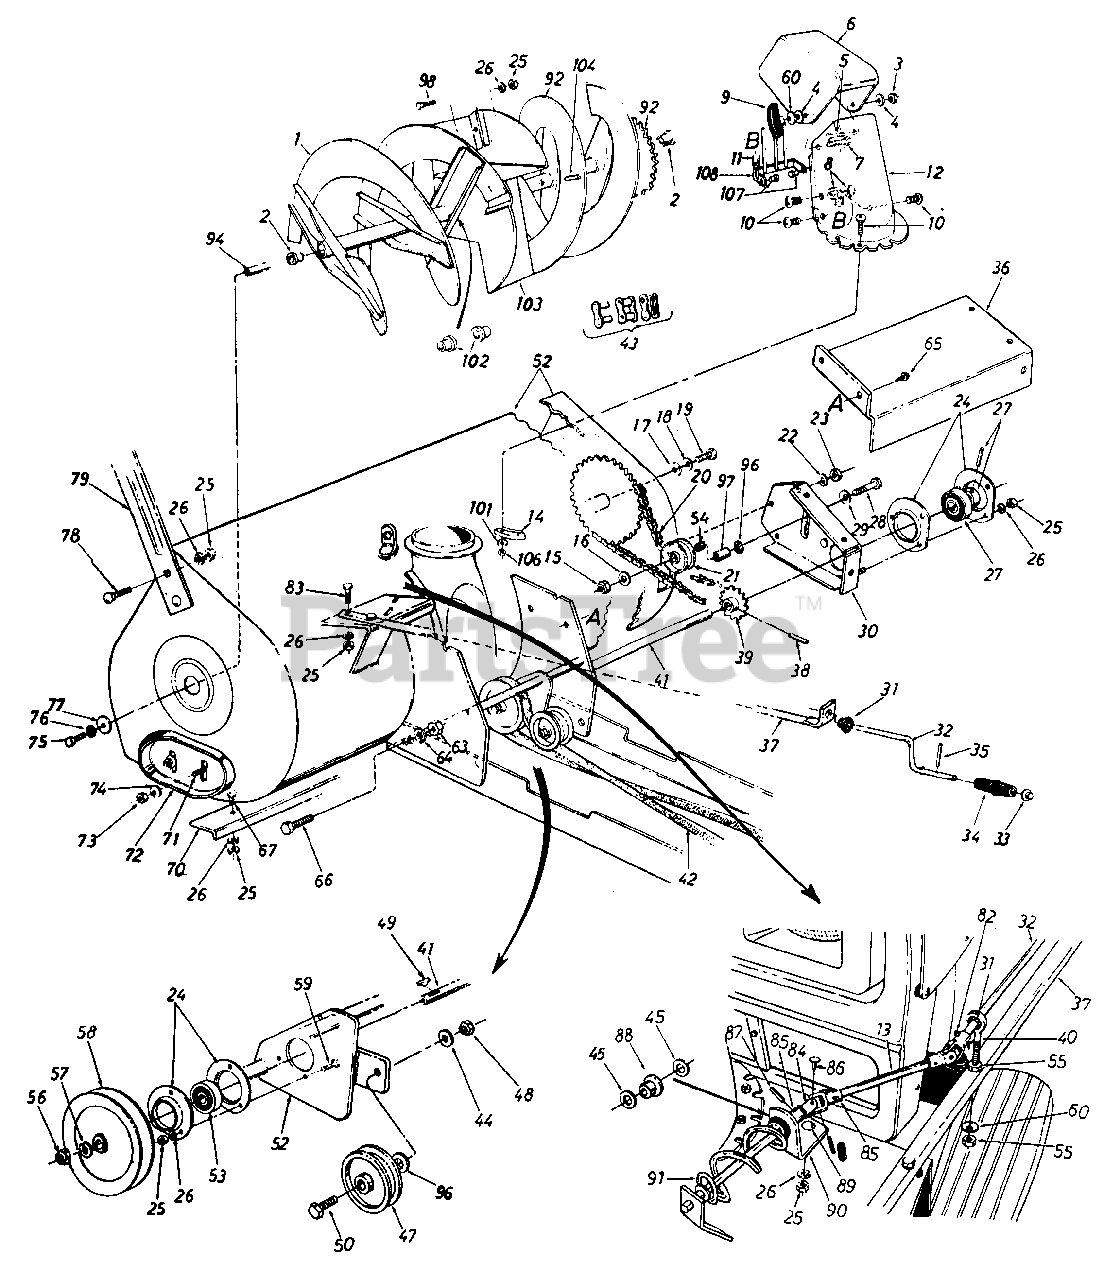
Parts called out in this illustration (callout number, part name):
3	Hex Cent. L.-Nut 5/16-18 Thd.
4	Fl.-Wash. .344" I.D.
5	Truss Mach. Scr. 5/16-18 x .75" Lg.
6	Upper Chute
7	Carriage Bolt 5/16-18 x 1.0" Lg.
8	Hex L-Nut 1/4-20 Thd.
9	Hand Knob
10	Truss Mach. Scr 1/4-20 x .75" Lg.
11	Ext. Spnng
12	Lower Chute
13	Chute Crank Extension Rod
14	Chute Flange Keeper
15	L.-Nut 3/8-16 Thd.
16	Fl. Wash.
17	Fl.-Wash.
18	Belleville Wash.
19	Hex Bolt 1/2-13 x 1.00" Lg.
20	#420 Chain 1/2" Pitch x 77 Links
21	Plastic Idler 2.00" O.D.
22	L.-Wash. 1/4" I.D.
23	Hex Nut 1/4-20 Thd.
24	Bearing Housing
25	Hex Nut 5/16-18 Thd.
26	L.-Wash. 5/16" I.D.
27	Self-Aligning Bearing
28	Hex Bolt 3/8-16 x 1.75" Lg.
29	Belleville Wash. 3/8" I.D.
30	Chain Guard Ass'y.
31	Nylon Bushing
32	Chute Crank .375 Dia. x 34.5" Lg.
33	Push Nut 3/8" Rod
34	Knob (Black)
35	Roll Pin
36	Drive Shaft Cover
39	14 Teeth Sprocket Ass'y.
40	Eyebolt 5/16-18 x 3.0" Lg.
41	Drive Shaft
42	"V" Belt
43	Master Link for #420 Chain
44	L.-Wash. 3/8" I.D.
45	Fl.-Wash. .385 I.D. x .62" O.D.
47	Fl.-Idler with Flanges
48	Hex Jam L.-Nut 3/8-16 Thd.
49	#61 Hi-Pro Key 3/16 x 5/8" Dia.
50	Hex Bolt 3/8-16 x 1.75" Lg.
52	Spiral Housing Ass'y.
53	Self Aligning Bearing
54	Sleeve Bearing .50" I.D.
55	Hex Nut 5/16-18 Thd.
56	Hex Nut 3/4-10 Thd.
57	L.-Wash. 3/4" I.D.
58	"V"Pulley .750" I.D. x 6.00 0. D.
59	Hex Sems Bolt 5/16-18 X .75 Lg.
60	Bell Wasll. .345" I.D. x .88 0. D.
63	Hex Nut 1/2-13 Thd.
64	L.Wash 1/2" I.D.
65	Hex Wash. Hd. Tap Scr. 1/4-20 x .50" Lg.
66	Hex Bolt 1/2-13 X 2.75" Lg.
67	Carriage Bolt 5/16-18 X .75"
72	Skid Shoe
73	Hex Jarn Nut 3/8-16 Thd.
74	Belleville Wash. 3/8" I.D.
75	Hex Bolt 1/2-13 X 1.OO" Lg.
76	Belleville Wash 1/2" I.D.
77	Fl. Wash.
78	Carriage Bolt 5/16-18 X .62 Lg.
79	Drift Cutter
82	Cotter Pin
83	Hex Bolt 5/16-18 X 1.50" Lg.
84	Joint Block
85	Joint Bracket Ass'y.
86	Oval Head Rivet
87	Spring Pin Roll 1/8" Dia. x .75 Lg.
88	Nylon Bushirlg
89	Carriage Bolt 5/16-18 x .75" Lg.
90	Chute Crank Bracket
91	Chute Crank Ass'y.
96	Flat Washer
97	Idler Spacer
98	Carriage Bolt 5/16-18 x .75" Lg.
101	Fl. Wash 1/4" I.D.
102	Plastic Bushing
106	Hex L.-Nut 1/4-20 Thd.
107	Shld. Nut 1/4 20 Thd.
